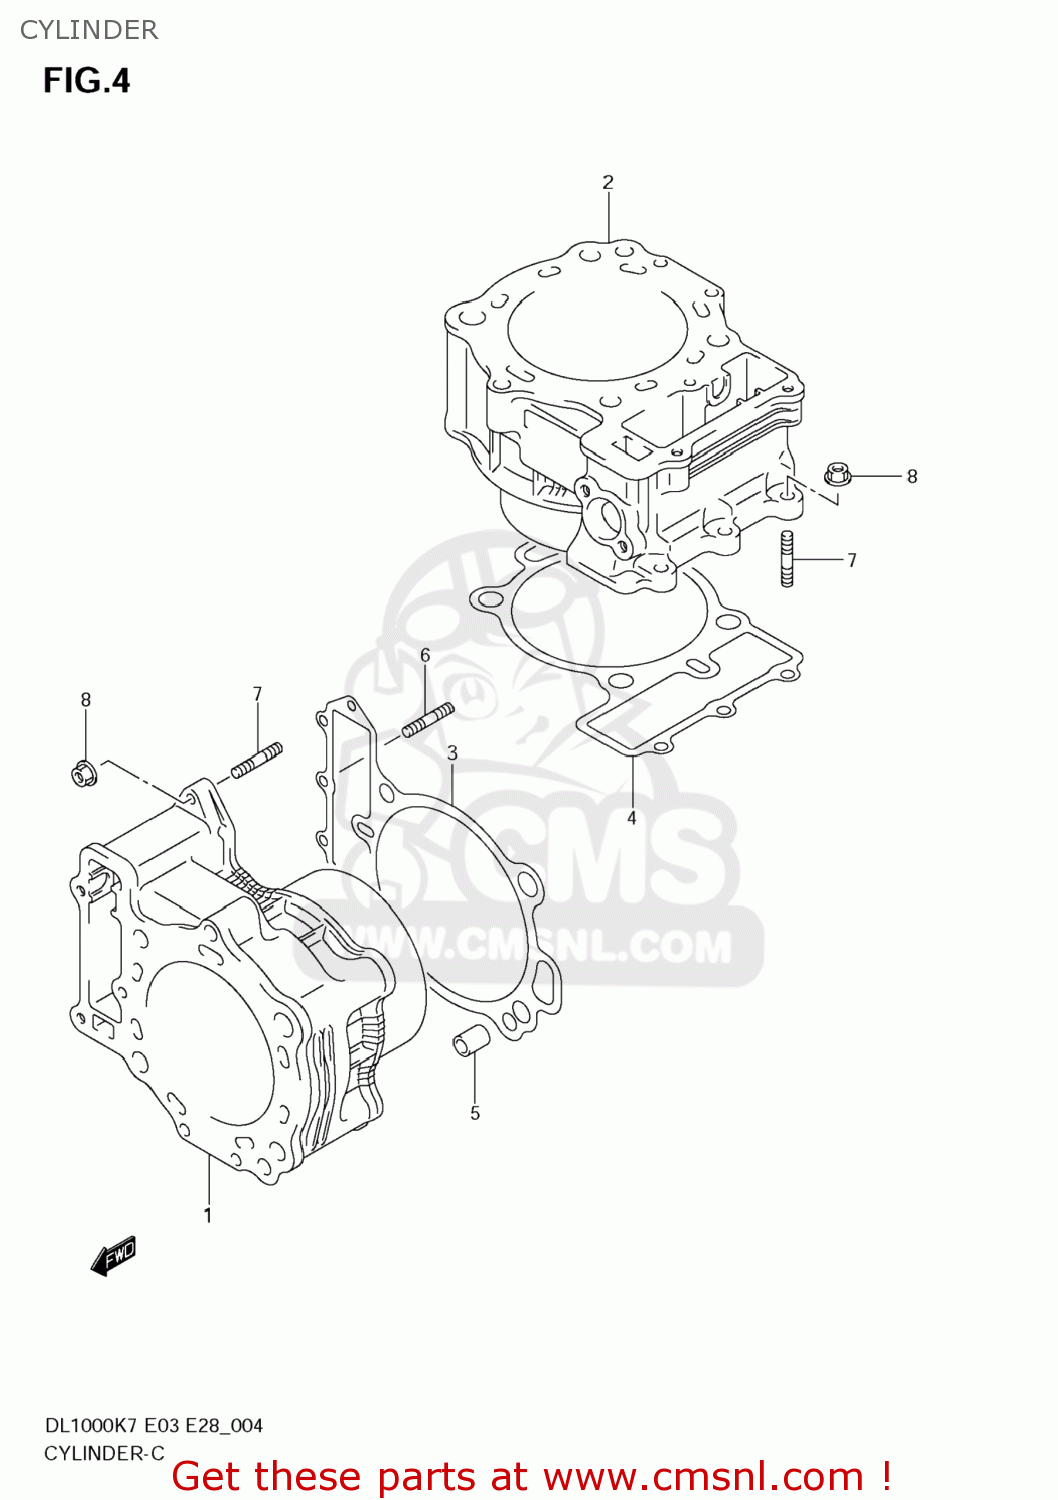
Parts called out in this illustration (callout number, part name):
1	CYLINDER,FR
2	CYLINDER,RR
3	GASKET,CYLINDER FR (NAS)
4	GASKET,CYLINDER RR (NAS)
5	PIN
6	BOLT,STUD
7	BOLT,STUD
8	NUT
